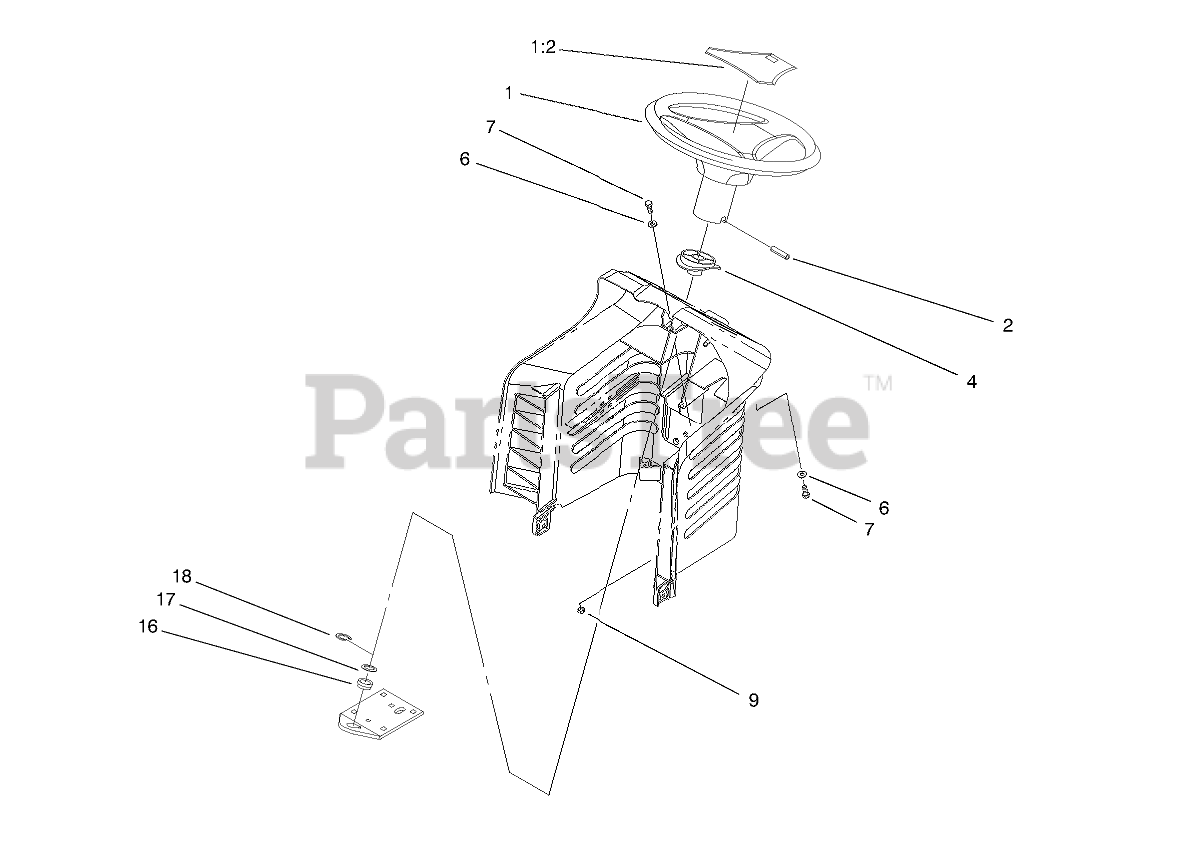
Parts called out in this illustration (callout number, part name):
1	Steering Wheel
1:2	COVER-WHEEL
2	PIN-ROLL
4	BUSHING-SLIDING
6	WASHER-FLAT
7	SCREW-HH
9	NUT-LOCK, NI
16	BEARING-FLANGE
17	WASHER-THRUST
18	E-RING
